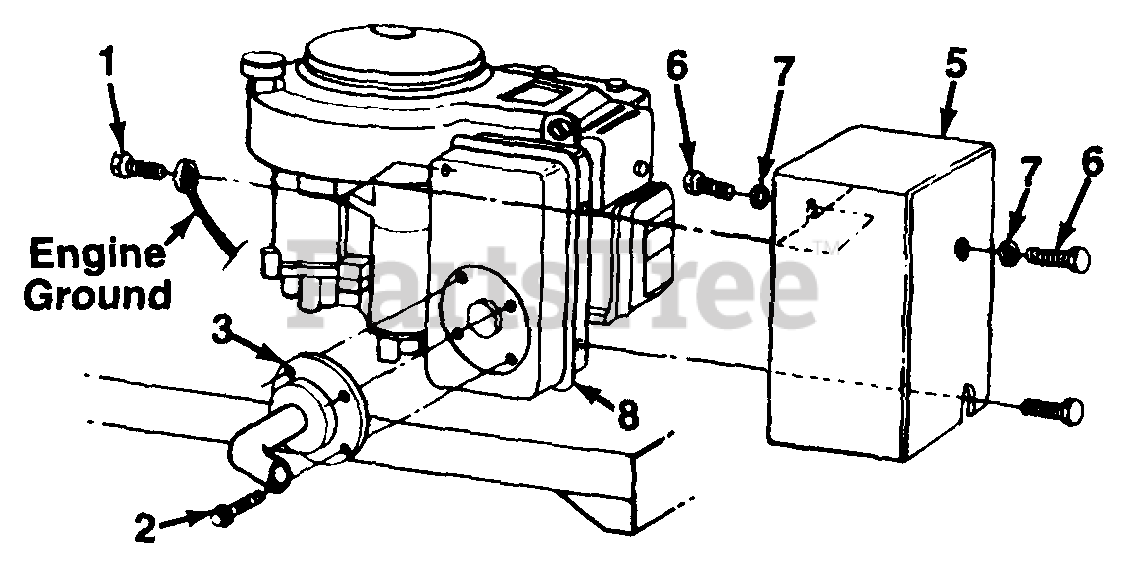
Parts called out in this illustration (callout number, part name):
1	Hex Bolt M6-1" x 10 MM Lg. (Gr. 5)
2	Hex Wash. Hd. F-Tap Scr. #8-32 x .38" Lg.
3	Exhaust Pipe Ass'y.
5	Muffler Heat Shield Ass'y.
6	Hex Cap Scr. M6-1" x 14 MM Lg.
7	Bell-Wash. .265" I.D. x .75" O.D.
8	Muffler - Supplied by Engine Manufacturer
